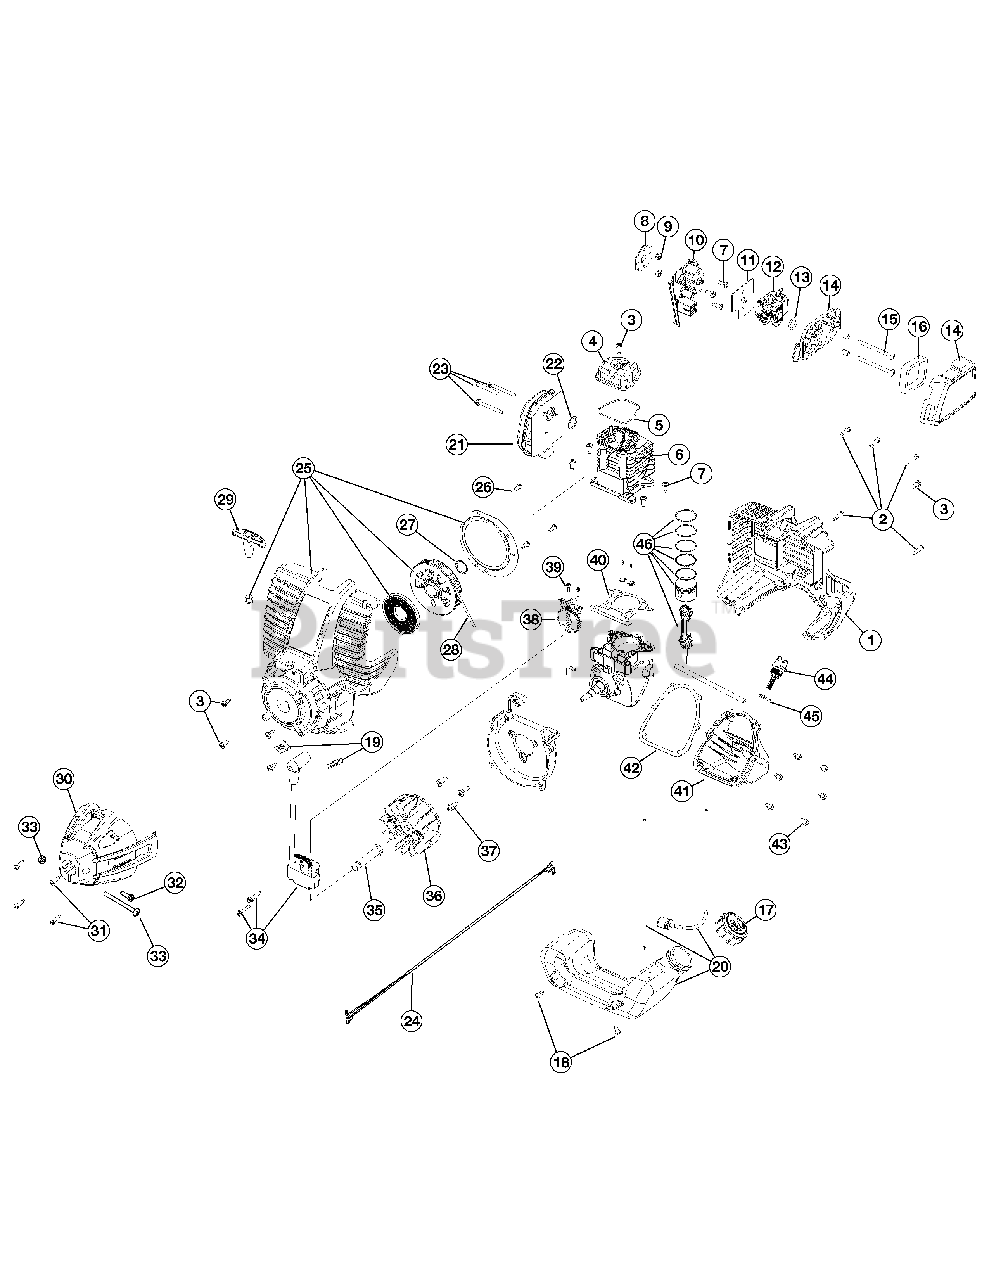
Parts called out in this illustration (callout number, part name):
1	Engine Cover
3	Screw
4	Valve Cover
5	Valve Cover Gasket
6	Cylinder Assembly (includes 5, 7 & 40)
7	Cylinder Screw
8	Insulator Gasket
9	Nut
10	Insulator (includes 11)
11	Carburetor Gasket
12	Carburetor w/Primer
13	Carburetor O-Ring
14	Air Filter Cover Assembly (includes 16)
15	Air Filter Mounting Screw
16	Air Filter
20	Fuel Tank Assembly (includes 17)
21	Muffler Assembly (includes 22 & 23)
22	Muffler Gasket
23	Muffler Mounting Screw
25	Starter Housing Assembly (includes 3, 19 & 26-29)
26	Plate Screw
27	Push Nut
29	Pull Handle
30	Clutch Cover Assembly (includes 31-33)
31	Cover Screw
32	Anti-Rotation Screw
33	Clamping Screw Assembly
34	Ignition Module Assembly
35	Square Nut Drive
37	Shroud Screw
38	Cam Bracket Assembly (includes 39)
39	Cam Bracket Screw
40	Cylinder Gasket
41	Oil Pan (includes 42 & 43)
42	Oil Pan Gasket
43	Oil Pan Screw
44	Dipstick Assembly (includes 45)
46	Piston Assembly
